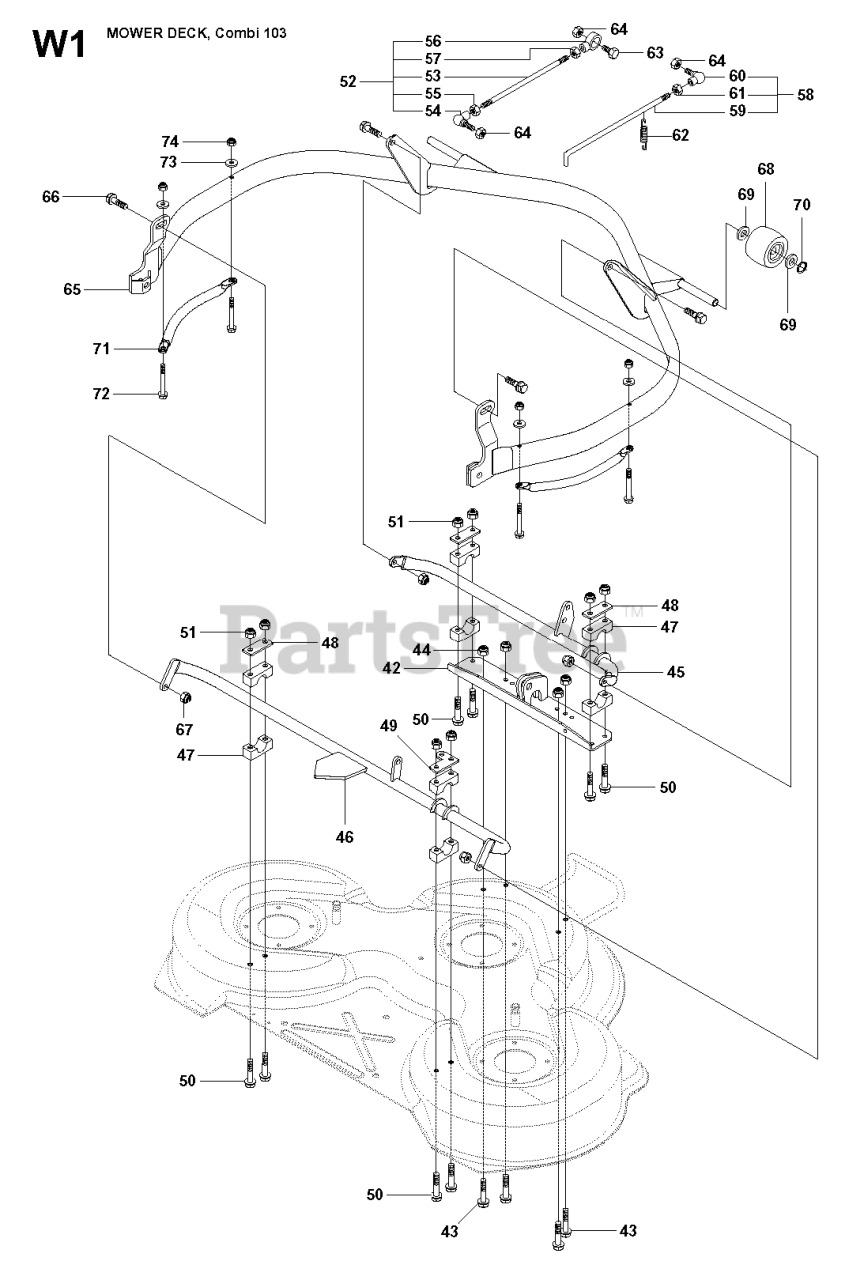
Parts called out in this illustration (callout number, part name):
44	LOCKNUT M8
51	LOCKNUT M8
52	PARALLEL RODY ASSY
57	NUT
58	CLUTCH ROD ASSY
64	NUT
65	PROTECTIVE TUBING
67	LOCKNUT M8
68	DECK ROLLER, FRONT
70	RETAINING RING SGA 15
73	WASHER
74	LOCKNUT M6
